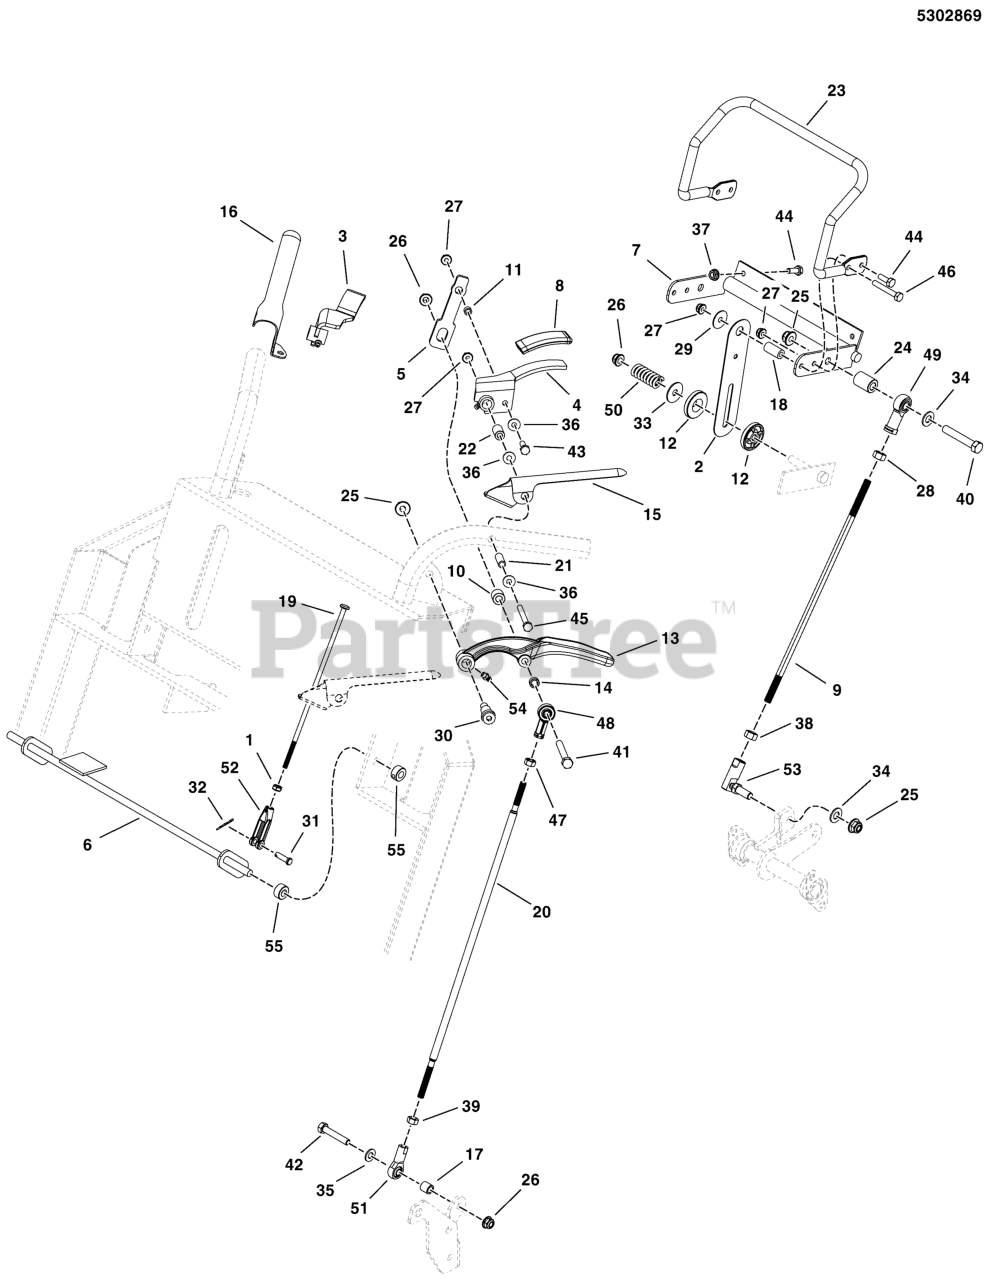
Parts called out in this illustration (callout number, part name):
1	HN, 1/4F GR5 YZ
2	PLATE, FRICTION CONTROL, SS
3	WELD, THUMB CONTROL, RH, FLAIL- RED
4	WELD, THUMB CONTROL, LH, FLAIL - RED
5	LINK, THUMB CONTROL - BLACK
6	WELD, ROD, SWITCH, SW-30 - RED
8	GRIP, FOAM, 1/8 X 1.13 X 2.75"
9	ROD, CRUISE CONTROL, SNP PRO WB
10	SPACER, .33 X .625 X .88, STEP, CZ
11	SPACER, .265 X .375 X .25, CZ
12	SPACER, .34 X 1.54 X .25 - UHMW
13	HANDLE, REVERSING - BLK
14	SPACER, .33 X .50 X .25, CZ
17	SPACER, .33 X .50 X .50, CZ
18	SPACER, .26 X .50 X 1.00
19	ROD, OPC LINK, SNP PRO WB
20	ROD, 5/16-24 X 33.2 LH-RH, CZ
21	SPACER, .26 X .38 X 1.25, CZ
22	SLEEVE, CRUISE CONTROL ROLLER
23	BAR, SPEED CONTROL, DIPPED
24	SPACER, .39 X .75 X 1.06
25	NUT, 3/8-16 HEX NYLOCK FLANGE
26	NUT, 5/16-18 HEX NYLOCK FLANGE
27	NUT, 1/4-20 HEX NYLOCK FLANGE
28	NUT, 3/8-24 HEX, LH
29	WASHER, 1/4 FENDER
30	BOLT, 3/8-16 X 1, 1/2 SHOULDER
31	PIN, CLEVIS, 1/4 X 7/8, PLATED
32	PIN, HAIR, .0585 X 1-1/8, 1/4 EYE, YZ
33	WASHER, 5/16 FENDER
34	WASHER, 3/8 SAE
35	WASHER, 5/16" SAE
36	WASHER, 1/4 SAE
37	NUT, 1/4-20 HEX SERR. FLANGE
38	NUT, 3/8-24 HEX
39	NUT, 5/16-24 HEX
40	BOLT, 3/8-16 X 2-1/4" GD5 CZ
41	BOLT, 5/16-18 X 3 GD5 YZ
42	BOLT, 5/16-18 X 1-3/4 GD5 YZ
43	BOLT, 1/4-20 X 1" GD5 CZ
44	BOLT, 1/4-20 X 3/4 GD5 YZ
45	BOLT, 1/4-20 X 3, GD5
46	BOLT, 1/4-20 X 1-3/4 GD5 YZ
47	NUT, 5/16-24 HEX, LH
48	BALL JOINT 5/16-24 LH FEMALE BRONZE RACE
49	ROD END, 3/8-24 LH FEMALE
50	SPRING-COMP, .428IDX2.50LGX.154WR, BZ
51	BALL JOINT 5/16-24 RH FEMALE BRONZE RACE
53	BALL JOINT, 3/8-24 FEM, STUD
54	GREASE FITTING, 1/4-28 STRAIGHT
55	COLLAR, 3/8 SET
